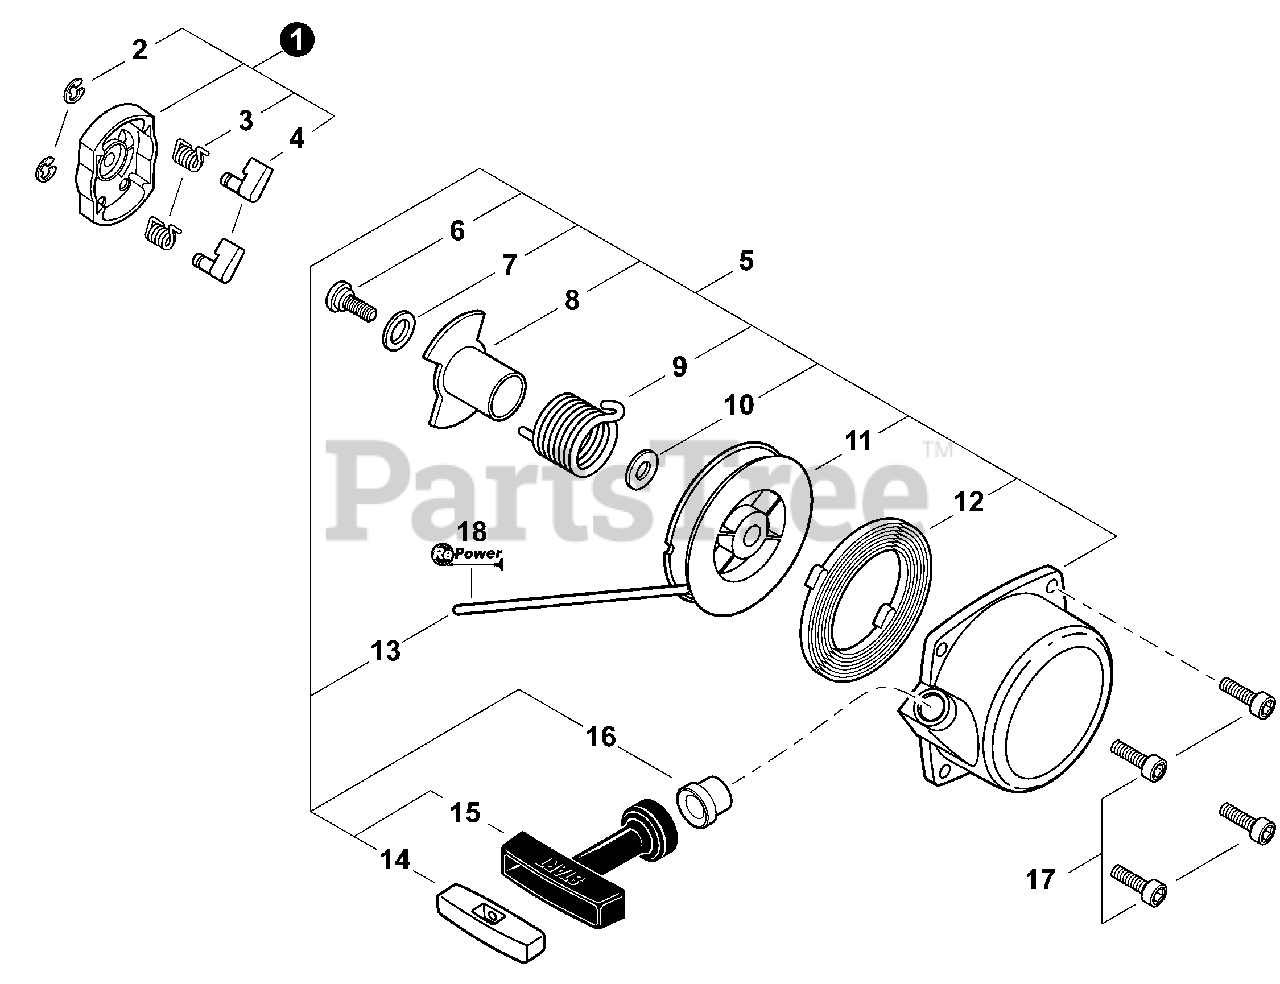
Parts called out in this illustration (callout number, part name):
1	PULLEY ASSY, STARTER
2	E-RING 4
3	SPRING, RETURN
4	PAWL, STARTER
5	STARTER ASSY, RECOIL
6	SCREW
7	WASHER, THRUST
8	PAWL CATCHER
9	SPRING, FRICTION
11	REEL, ROPE
12	SPRING, RECOIL
13	ROPE, STARTER 3.5×1000mm
14	RETAINER, ROPE
15	GRIP, STARTER
16	GUIDE, ROPE
17	SCREW 5×16
18	ROPE, STARTER - REPOWER BULK
